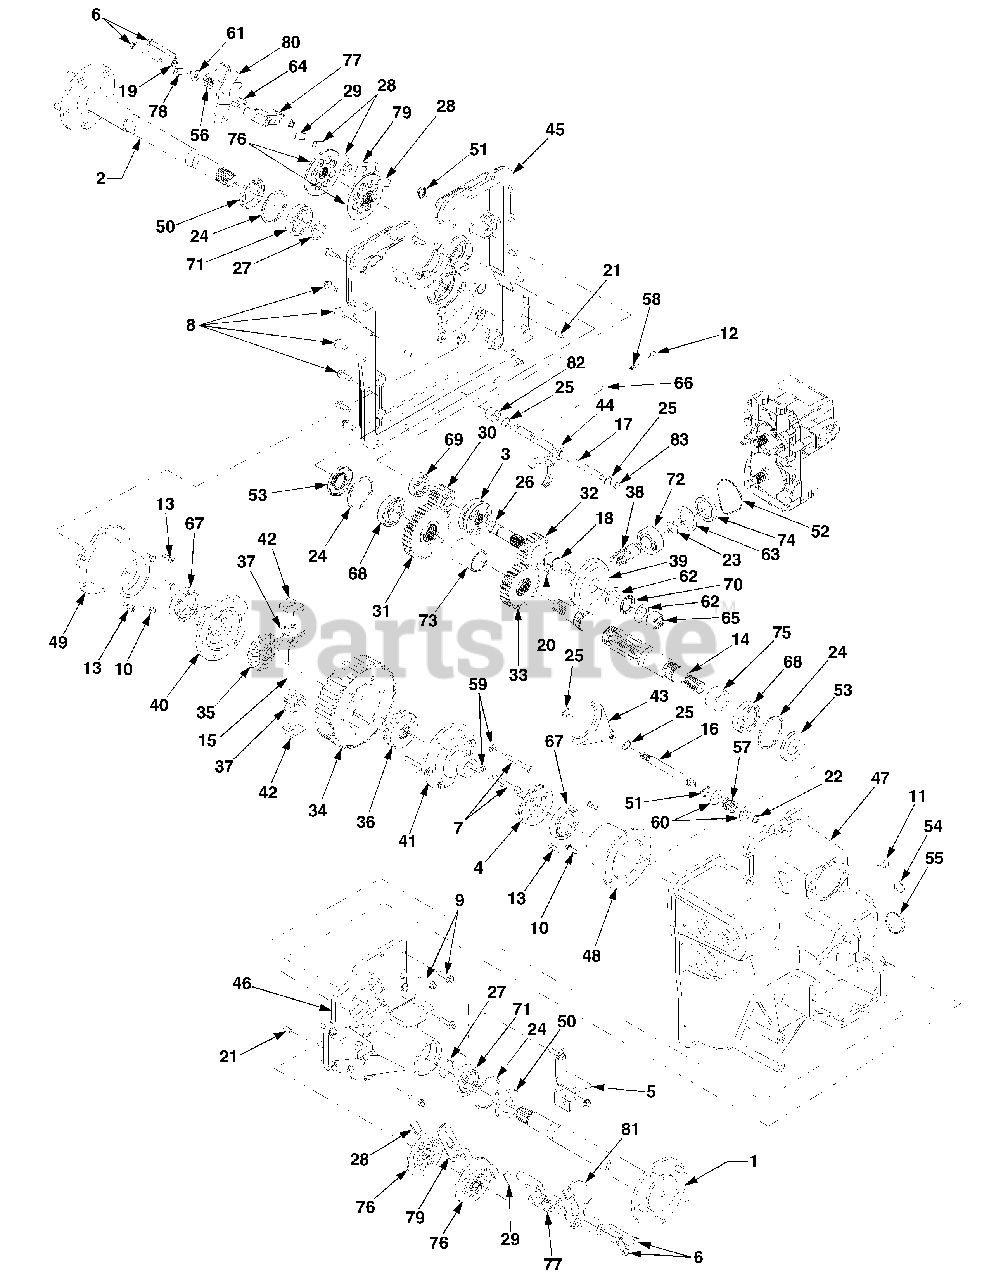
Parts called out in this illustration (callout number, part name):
1	Shaft, Axle RH
2	Shaft, Axle LH
3	Collar Assembly, Hi-Lo
4	Collar Assembly, Diff Lock
5	Bracket, Diff. Lock
6	Screw, Hex Cap, 5/16-18 x 2.75 GR5
7	Screw, Hex Cap, 5/16-18 x 2.5 GR5
8	Screw, Hex Wash. Hd. Tapp, 5/16-18 x 1.0
9	Screw, Hex Wash. Hd. Tapp, 5/16-18 x 1.25
10	Screw, Hex Cap, w/Patch 5/16-18 x.75 GR5
11	Screw, Plug, M14 x 1.5 x .827
12	Screw, Set, 5/16-18 x .375
13	Screw, Shoulder .309 x .375: 1/4-20
14	Shaft, Output, 11T
15	Shaft, Cross, .625 x 3.95
16	Shaft, Diff. Lock Actuator
17	Shaft, Hi-Lo Actuator
18	Shaft, Drive
19	Nut, Hex Insert Lock, 5/16-24
20	Key, Woodruff, 1/4 x 3/4
21	Pin, Dowel, .25 x .75
22	Ring, Retaining
23	Ring, Snap
24	Ring, Retaining
25	Clip, Rotor
26	Ring, Retaining
27	Ring, Retaining
28	Pad, Brake
29	Plate, Brake Puck
30	Gear, Spur, 12T
31	Gear, Spur, 34T
32	Gear, Spur, 19T
33	Gear, Spur, 27T
34	Gear, Spur, 56T
35	Gear, Bevel, 16T
36	Gear, Bevel, 16T Lock
37	Gear, Bevel, 10T Diff.
38	Gear, Spiral Bevel, 13T
39	Gear, Spiral Bevel, 54T
40	Cover, Differential
41	Cover, Differential Lock
42	Block, Thrust
43	Yoke, Diff. Lock Actuator
44	Yoke, Shift, Hi-Lo
45	Cover, Trans. Large
46	Cover, Trans. Small
47	Housing, Trans.
48	Housing, Axle Inner - RH
49	Housing, Axle Inner - LH
50	Seal, Oil
51	Seal, Oil
52	Seal, Gland
53	Seal, Oil
54	Plug, Oil
56	Spring, Torsion
57	Spring, Compression, .845 x 1.0
58	Spring, Compression, .24 x .563
59	Washer, Lock, 5/16
60	Washer, Flat, .597 x 1.0 x .04 ..
61	Washer, Flat, .343 x .88 x .062
62	Washer, Thrust
63	Washer, Flat, 1.52 x 2.0 x .030
63	Washer, Flat, 1.52 x 2.0 x .005
63	Washer, Flat, 1.52 x 2.0 x .015
64	Pin, Brake Actuating
65	Bearing, Needle
66	Ball, Detent
67	Bearing, Ball
68	Bearing, Ball
69	Bearing, Ball
70	Bearing, Needle Thrust
71	Bearing, Ball
72	Bearing, Ball
73	Spacer, 1.51 x 1.75 x 2.41
74	Spacer, 1.515 x 2.039 x .335 ...
75	Spacer, 1.26 x 1.625 x .853
76	Disc, Brake
77	Yoke, Brake
78	Bracket, Brake Anti Rotation
79	Plate, Puck Retainer
80	Arm, Brake Actuator - LH
81	Arm, Brake Actuator - RH
82	Spacer, .573 x .938 x .832
83	Plug, .437 x .16
